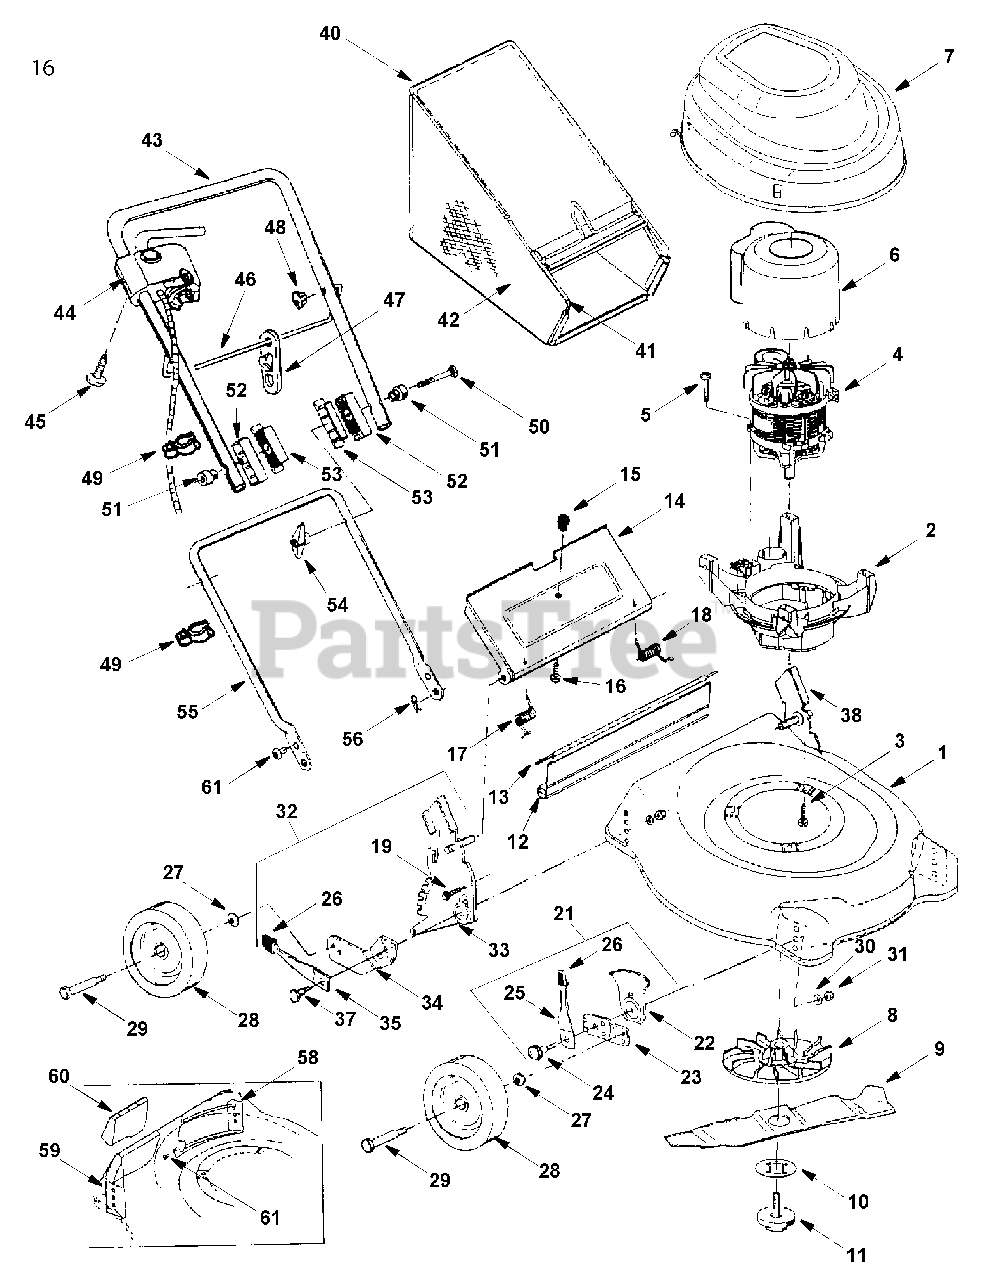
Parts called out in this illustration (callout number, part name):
1	19" Deck
2	Motor Support
3	Screw
4	Electric Motor 115V, 1500W
5	Screw
6	Air Guide Cover
8	Blade Hub Assembly
9	Blade
10	Locking Plate
11	Screw, Blade
12	Rear Flap
13	Rear Flap Wire
14	Chute Door
16	Truss Mach Scr #10-24 X .38
17	RH Torsion Spring
18	LH Torsion Spring
19	Hex Index Washer Screw 1/4-14 X .625
21	Height Adj. Ass’y RH (w/knob)
21	Height Adj. Ass’y LH (w/knob)
22	Height Adjuster Plate
24	Shoulder Screw .50 Dia.
25	Spring Lever Ass’y w/knob
26	Knob
27	Bell. Washer .375 ID X .870 OD X .063
28	Wheel 8" X 1.8", Gray
29	Axle Bolt
30	Bell. Washer .38 ID X 1.38 OD X .06
31	Hex Nut 3/8-16 Gr. 2
34	Pivot Bar RH SP
34	Pivot Bar LH SP
35	Spring Lever SP
37	Shoulder Screw .50 Dia.
38	Handle Brkt. Ass’y-LH
42	Grasscatcher Bag w/logo
43	Upper Handle
44	Switch Plug Combination
45	Screw
46	Guide Rod
48	Knob - ERS Guide 1/4-20
49	Cable Guide
50	Carriage Bolt 5/16-18 x 3.00
51	Insulator Knob
52	Upper Handle Insulator
53	Lower Handle Insulator
54	Wing Nut
55	Lower Handle
56	Int. Cotter Pin .072 X 1.13" Lg.
57	Front Baffle
58	Rear Baffle
59	Right Rear Baffle
60	Rear Mulch Plug
61	Torx Mach. AB-Tapp Scr. 1/4-14 X .625"
